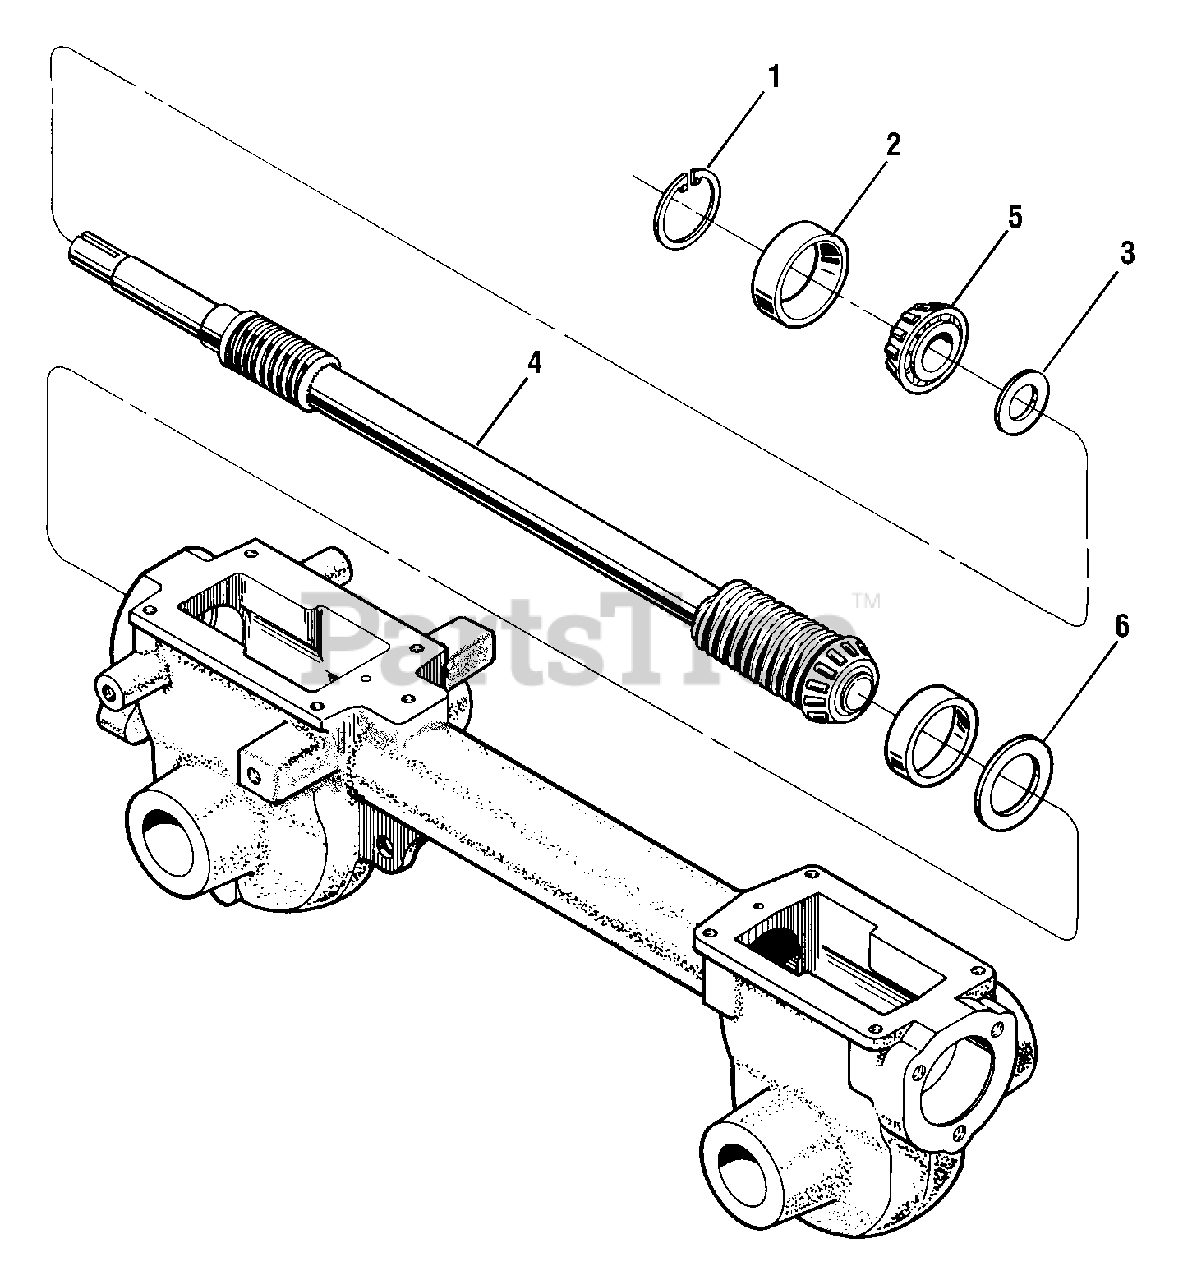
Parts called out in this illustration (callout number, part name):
1	Snap Ring
2	Drive Shaft Bearing Cup
3	Support Washer, Rear
4	Drive Shaft
5	Drive Shaft Bearing Cone
6	Shim, Rear Bearing Cap,.010" thick
